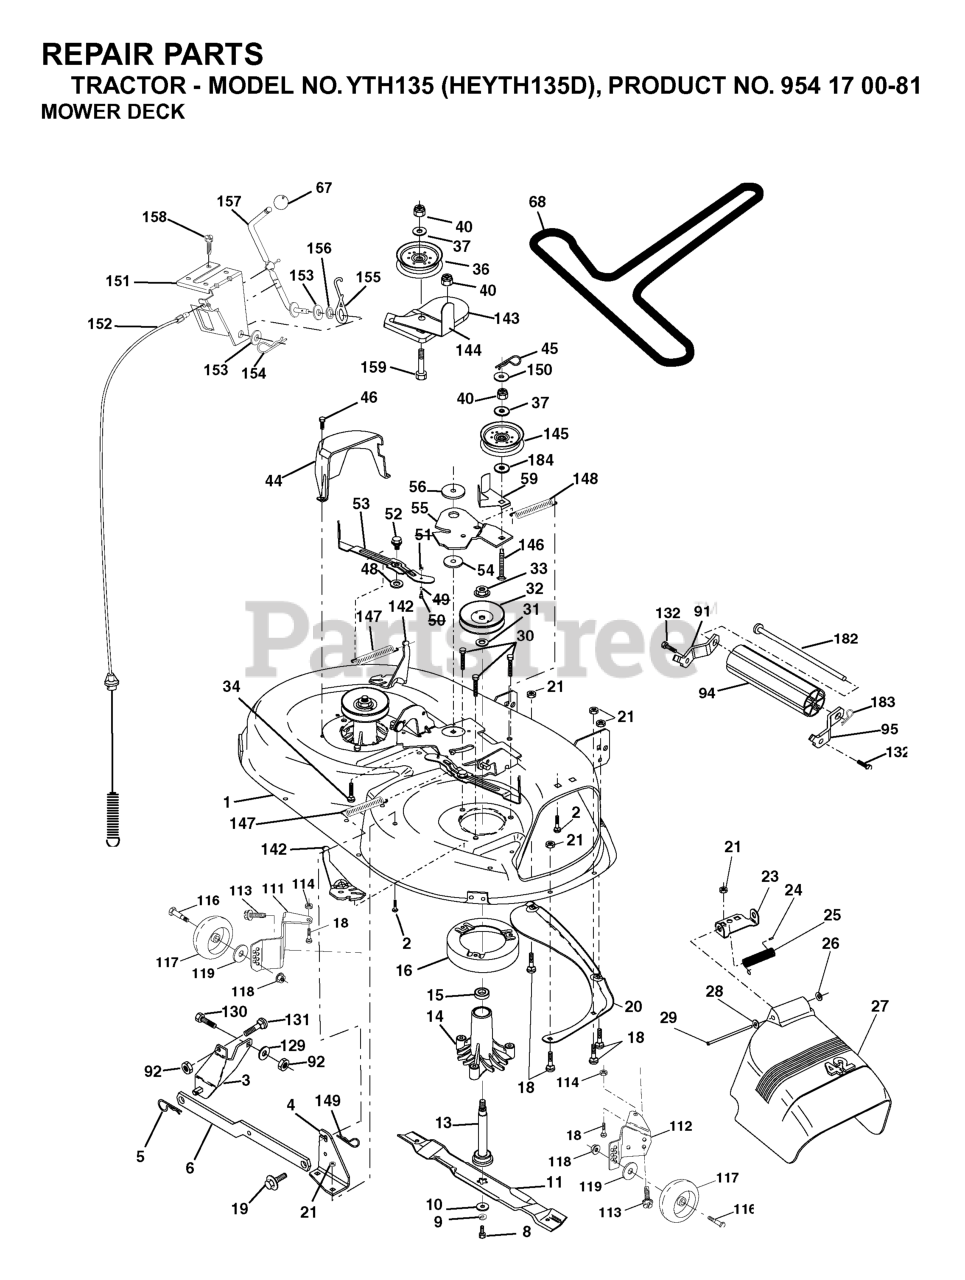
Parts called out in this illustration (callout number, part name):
1	42" DECK KIT
2	RP BOLT 5/16-18 X3/4 ZN/YEL GR
3	BRKT ASM SWAY BAR
4	BRACKET SWAY BAR 42" DECK
5	RETAINER-SPRNG RB
6	BAR SWAY DECK
8	BLADE BOLT
9	LOCKWASHER
10	WASHER.BLADE
11	42" HI-LIFT BLADE
13	SHAFT ASM VENT
14	HOUSING.MANDREL.VENTED (MACHD)
16	STRIPPER.MANDREL.ROUND.BLACK
18	BOLT
19	BOLT SHD 5/16-18
20	BAFFLE.VORTEX
21	LOCKNUT
23	BRKT, DEFL. MOWER
24	CAP-SLEEVE LT
25	SPRING TORSION
26	NUT PUSH M
27	SHIELD DEFLECTOR
28	Washer 11/32 x 5/8 x 16 Ga SD
29	ROD.HINGE
30	SCREW, WASHER HEAD
31	WASHER
32	PULLEY/MANDREL
33	NUT, FLG TOPLOCK 9/16"
36	FLAT IDLER PULLEY
37	WASHER
44	GUARD MANDREL LH BLACK
45	RETAINER M
46	SCREW.1/4-20X5/8
49	ROLLER ASM CAM FOLLOWER
52	BOLT.SHOULDER.5/16-18
53	ARM
55	ARM IDLER 42" MOWER LT/YT
56	SPACER.RETAINER.MOWER
59	GUARD, BELT
67	KNOB T (3/8 HOLE)
91	BRACKET ASM NOSEROLLER LH
92	NUT
94	NOSE ROLLER
95	BRACKET ASM NOSEROLLER RH
111	BRACKET, WHEEL
112	BRACKET, WHEEL
113	Screw Tapping 3/8-16 x .625
114	NUT
116	BOLT M
117	WHEEL.GAUGE.STANDARD
118	LOCKNUT
119	WASHER.5/16.FLAT.STE.STD.
129	WASHER
131	BOLT D
132	SCREW, 3/8-16X3/4
142	ARM SPRING BRAKE MOWER
143	BRACKET, ARM IDLER
144	DNO KEEPER.BELT.42".CLUTCH.CBL
145	PULLEY
146	BOLT, CARRIAGE IDLER BLACK
148	IDLER RETURN SPRING
149	SPRING.RETAINER.YELLOW.ZINC
151	BRACKET.CLUTCH.CABLE
152	CABLE.CLUTCH.42"
153	WASHER FLAT 3/8"
154	SPRING RETAINER
155	SPRING RETENTION LEVER
156	SPACER.CLUTCH.CABLE
157	ROD CLUTCH CABLE 3/8"
158	SCREW
182	ROD ROLLER NOSE STANDARD
183	SPRING RETAINER
184	WASHER
